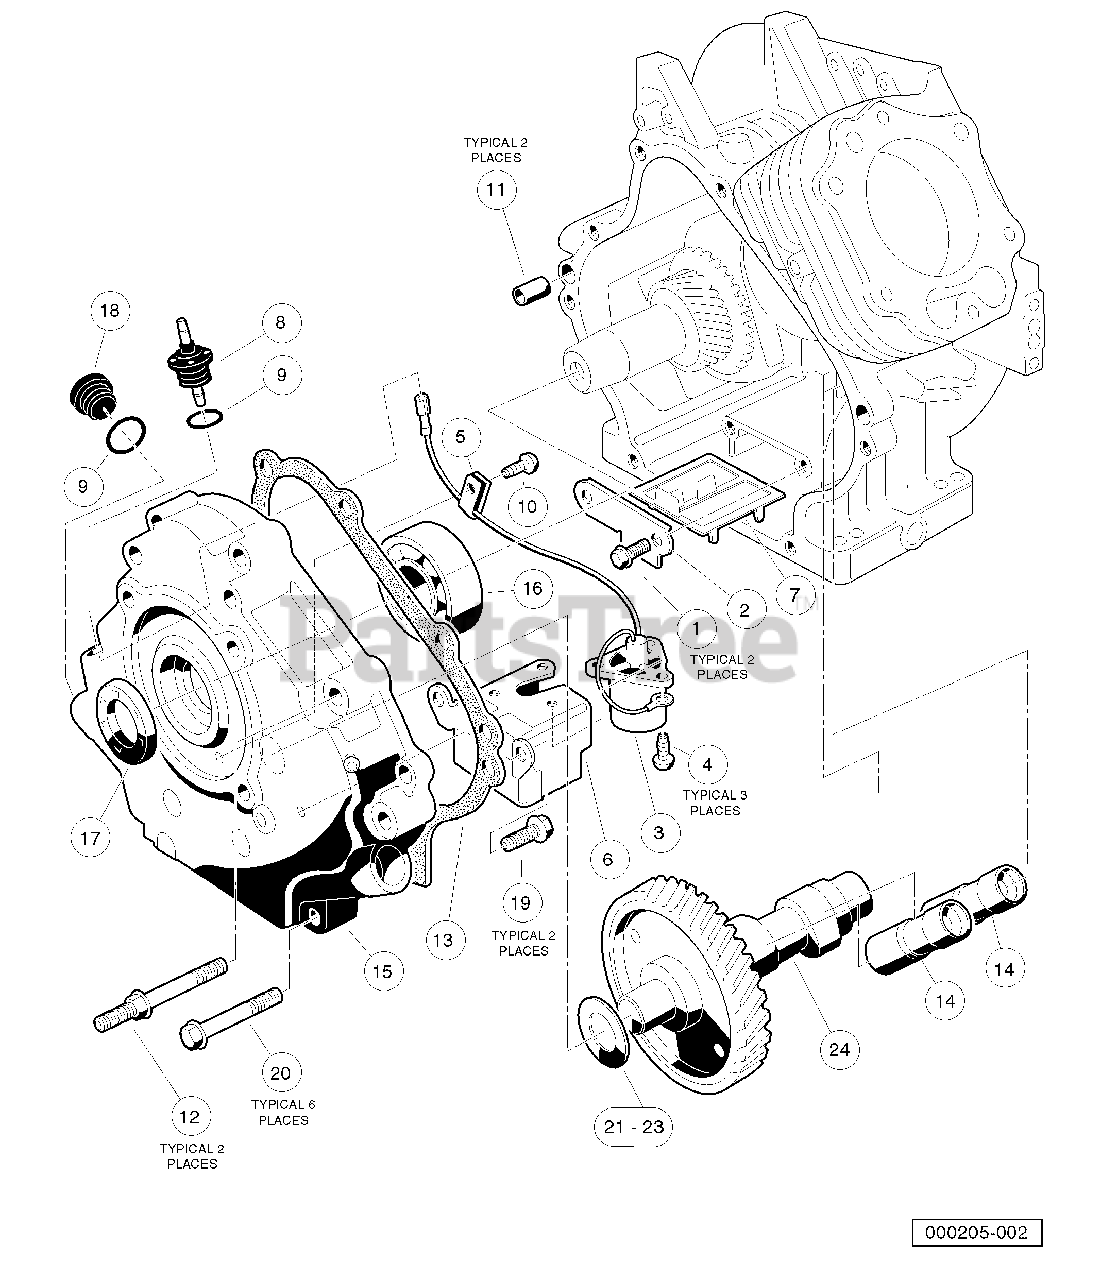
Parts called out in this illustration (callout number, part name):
1	Bolt, Flange Head, M5 x 0.8 x 8 mm
2	Plate, Oil Filter Screen
3	Sensor, Oil Level
4	Screw, Cross Pan-Head, M4 x 0.7 x 8 mm
6	Bracket, Switch, Oil Level
7	Screen, Oil Filter
8	Connector, Cord
12	Bolt, Two-Ended, M8 x 1.25 x 69 mm
13	Gasket, Crankcase Cover
14	Adjuster, Lash
15	Cover Crankcase
16	Bearing, Ball
20	Screw, M8-1.25 X 45mm Hex
24	Camshaft, FE350 without ACR, 44-Tooth
